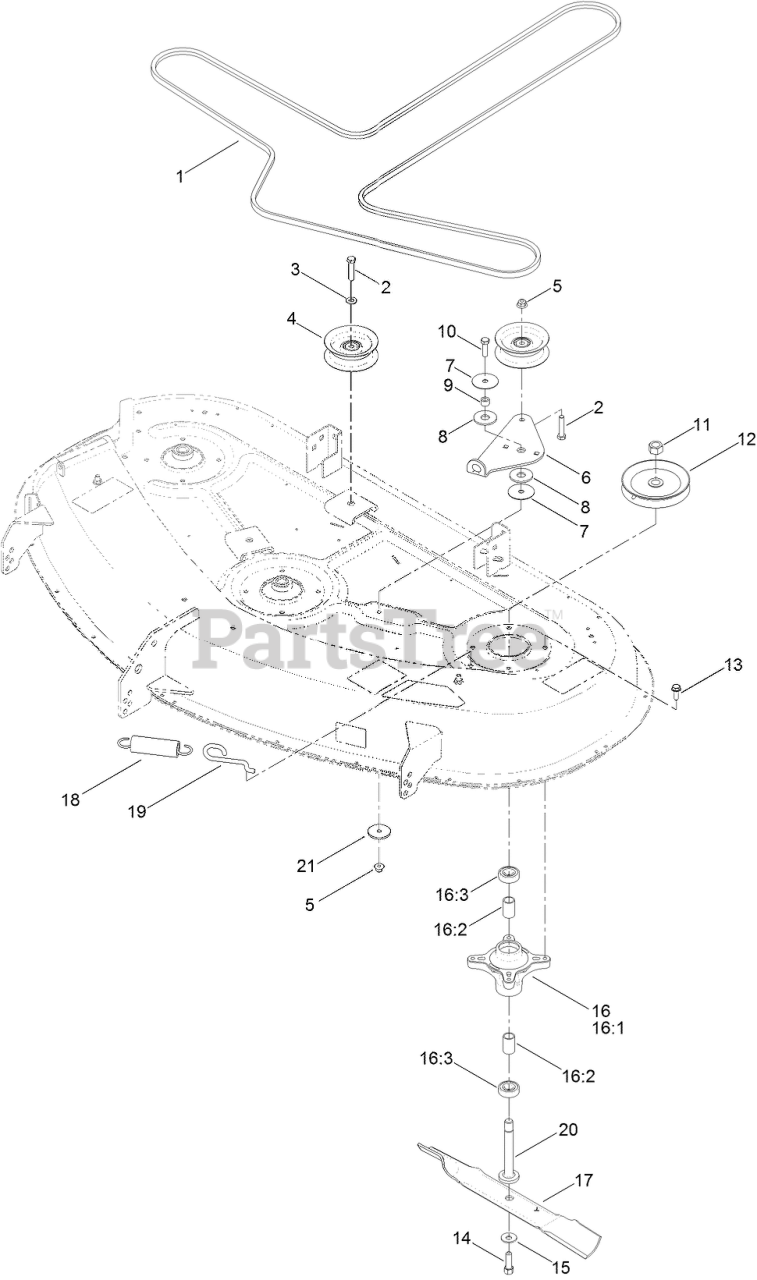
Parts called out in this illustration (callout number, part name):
1	BELT-V
2	SCREW-HH
3	WASHER-FLAT
4	PULLEY-IDLER, FLAT
5	NUT-HF, NI
6	ARM-IDLER
7	WASHER
8	WASHER-FRICTION, COMPOSITE
9	SPACER
10	SCREW-HH
11	NUT-HEX
12	PULLEY ASM
13	SCREW-TAPTITE
14	SCREW-HH
15	WASHER-BELLEVILLE
16	SPINDLE ASM
16:1	SPINDLE
16:2	SPACER
16:3	BEARING-BALL
17	BLADE-HI LIFT, 18.75 INCH
18	SPRING-EXTENSION
19	HOOK-RETURN, SPRING
20	SHAFT-SPINDLE
21	WASHER-REBOUND
